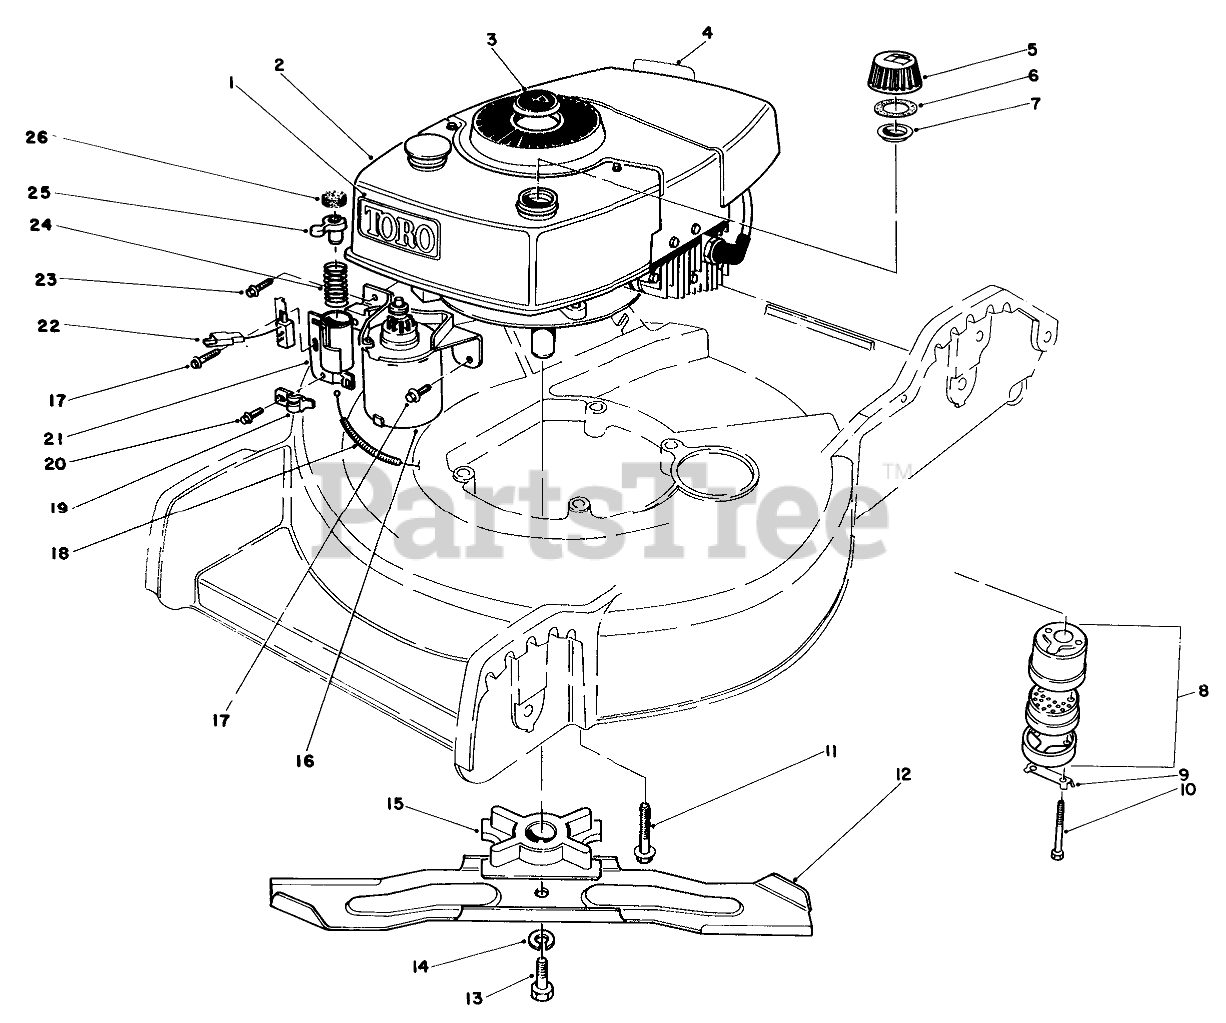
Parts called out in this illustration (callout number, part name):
1	Decal Tow
2	Engine
3	PLUG BUTTON
4	Decal-Maintenan
5	Gas Cap Assembly (Incl. Ref. #6 & 7)
6	GASKET
7	GAS CAP BAFFLE
8	Muffler Assembly (Incl. Ref. #9 & 10)
9	CLIP - LOCKING
10	SCREW-HH
11	3/8-16 X 2 CAPSCREW
12	Blade
13	SPECIAL SCREW
14	WASHER-LOCK
15	BLADE RETAINER
16	STARTER MOTOR ASM
17	SCREW
18	BRAKE CABLE-SUZUKI
19	CABLE CLAMP
20	SCREW
21	TUBE W A
22	PUSH BUTTON SWITCH
23	Screw
24	COMPRESSION SPRING
25	Plunger
26	Pad-Friction
